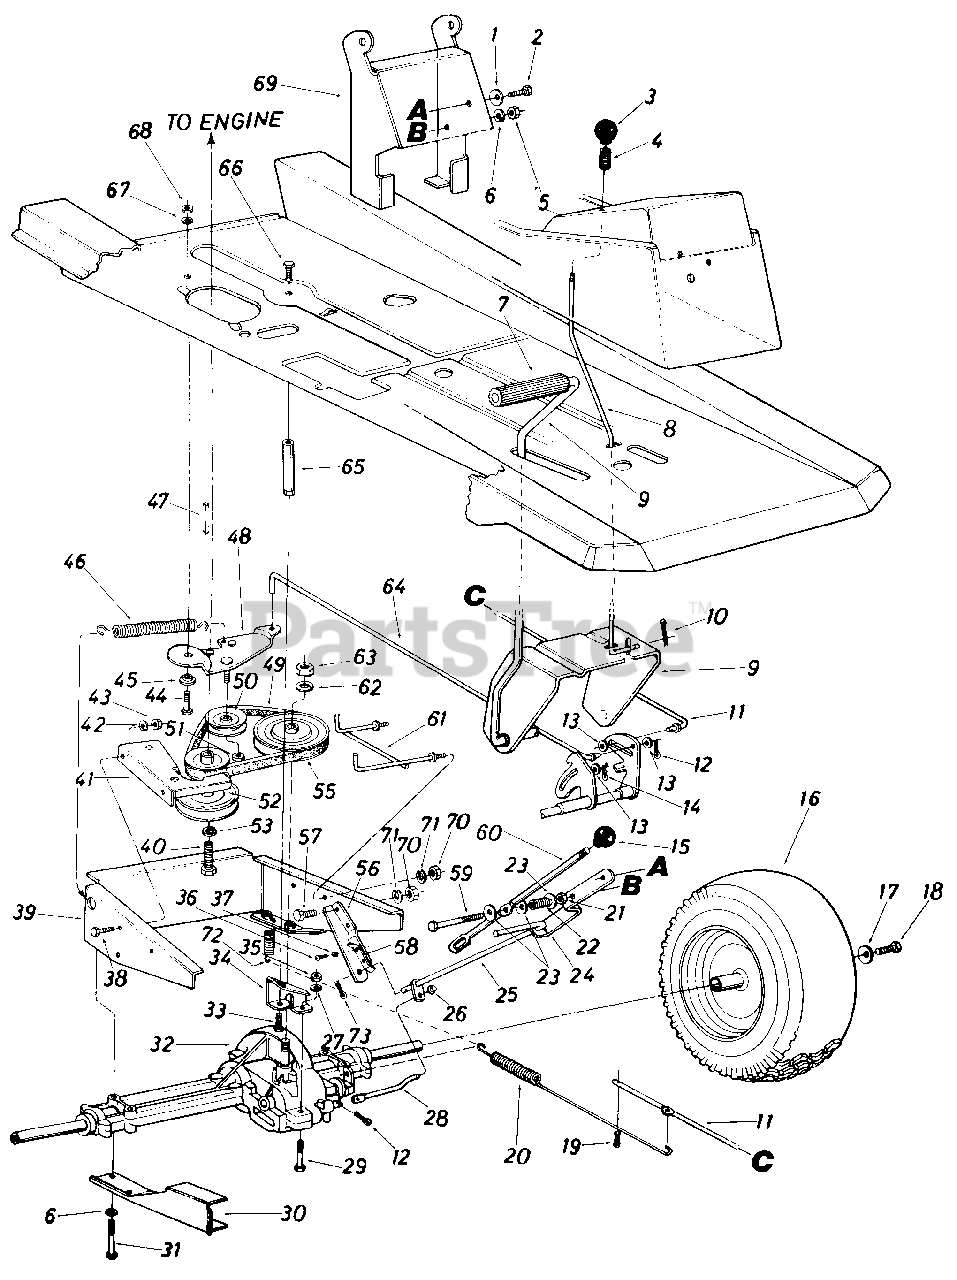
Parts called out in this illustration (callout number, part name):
1	Bell-Wash. .345" I.D. x .88" O.D.
2	Hex Wash. Hd. AB-Tap Scr. 1/4 x .62" Lg.
3	Ball Knob
4	Compression Spring
5	Hex Nut 5/16-18 Thd.
6	L-Wash. 5/16" I.D.
7	Foot Pad
8	Brake Locking Rod
9	Clutch-Brake Pedal Ass'y.
10	Cotter Pin 3132" I.D. x 3/4" Lg.*
11	Brake Rod
12	Cotter Pin 1/8" x 1.0" Lg.
13	Fl-Wash. .330" I.D. x .68" O.D.
14	Intern. Cotter Pin 5/16" Dia.
15	GearShift Knob
16	Rear Whee I Ass 'y.
17	Bell-Wash. .345" I.D. x ..88 O.D.
18	Hex L-Bolt 5/16-24 x .75" Lg.
19	Cotter Pin 118" Dia. x 1.25" Lg.
20	Ext. Spring .75" O.D. x 17.0" Lg.
21	Hex Nut 5/16-18 Thd.
22	Spring
23	Bell-Wash. .345" I.D. x .88" O.D.
24	Shift Lever Brk't.
25	Shift Lever Ass'y.
26	Cap Speed Nut 1/4" Rod
27	L-Wash. 1/4" I.D.
28	Shift Rod
29	Hex Bolt 1/4-20 x 1.75" Lg.
30	Lower Outside Engine Belt Guard
31	Hex Bolt 5/16-18 x 2.75" Lg.
32	Transaxle Comp.
33	Hex Bolt 3/8-24 x .75" Lg.
34	Torque Rod Bracket
35	Hex Nut 1/4-20 Thd.
36	C-Sink AB S-Tap Scr. #8 x .50" Lg.
37	Push-ln Nut #10
38	Hex Bolt 1/4-20 x .75" Lg.
41	Upper Engine Belt Guard
42	L-Wash. 1/4" I.D.
43	Hex Nut 1/4-20 Thd.
44	Hex Bolt 5/16-18 x .75" Lg.
45	Shoulder Spacer
46	Ext. Spring
47	Sq. Key 1/4" x 2 00" Lg.
48	Id ler Bracket Ass'y.
49	5L "V"-Belt 30" Lg.
50	"V"-ldler Pulley
51	Hex Insert L-Nut 3/8-24 Thd.
52	Engine Pulley
53	L-Wash. 7/16" I.D.
55	Transaxle Pulley 6.0" O.D.
56	Shift Lever Support
57	Hex Bolt 1/4-20 x .62" Lg.
58	Spring Switch
59	Hex Bolt 5/16-18 x 2.25" Lg.
60	Upper Shift Lever
61	Belt Trap
62	L-Wash. 1/2" I.D.
63	Hex Nut 1/2-13 Thd.
64	Clutch Rod
65	Torque Rod 4.325" Lg.
66	Hex Bolt 3/8-24 x .75" Lg. Grade 5
67	L-Wash. 5/16" I.D.
68	Hex Nut 5/16-18 Thd.
69	Front Seat Bracket
70	Hex Nut 1/4-20 Thd.
71	L-Wash. 1/4" I.D.
72	Brake Return Spring 3.18" Lg.
73	Cotter Pin 3/32" Dia. x .75" Lg.
